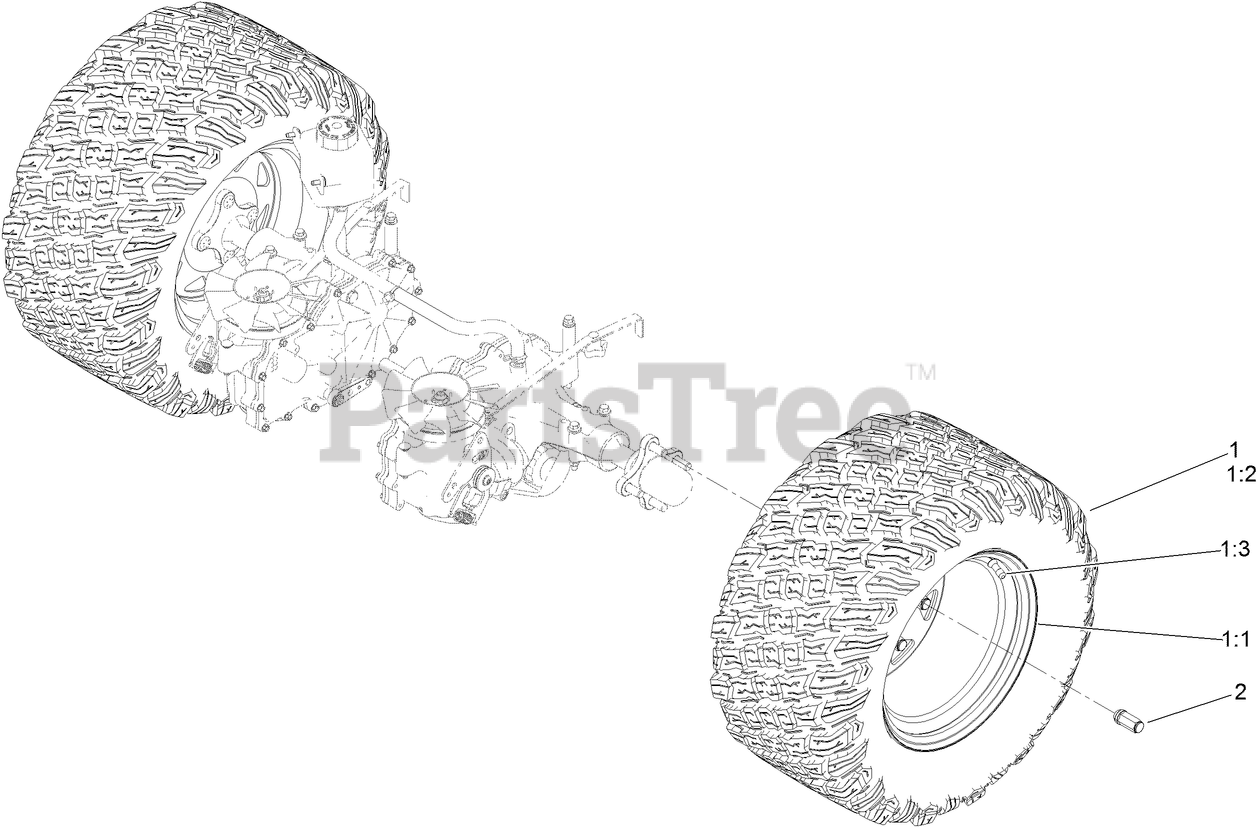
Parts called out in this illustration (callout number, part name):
1	WHEEL AND TIRE ASM
1:1	RIM-WHEEL
2	NUT-LUG
